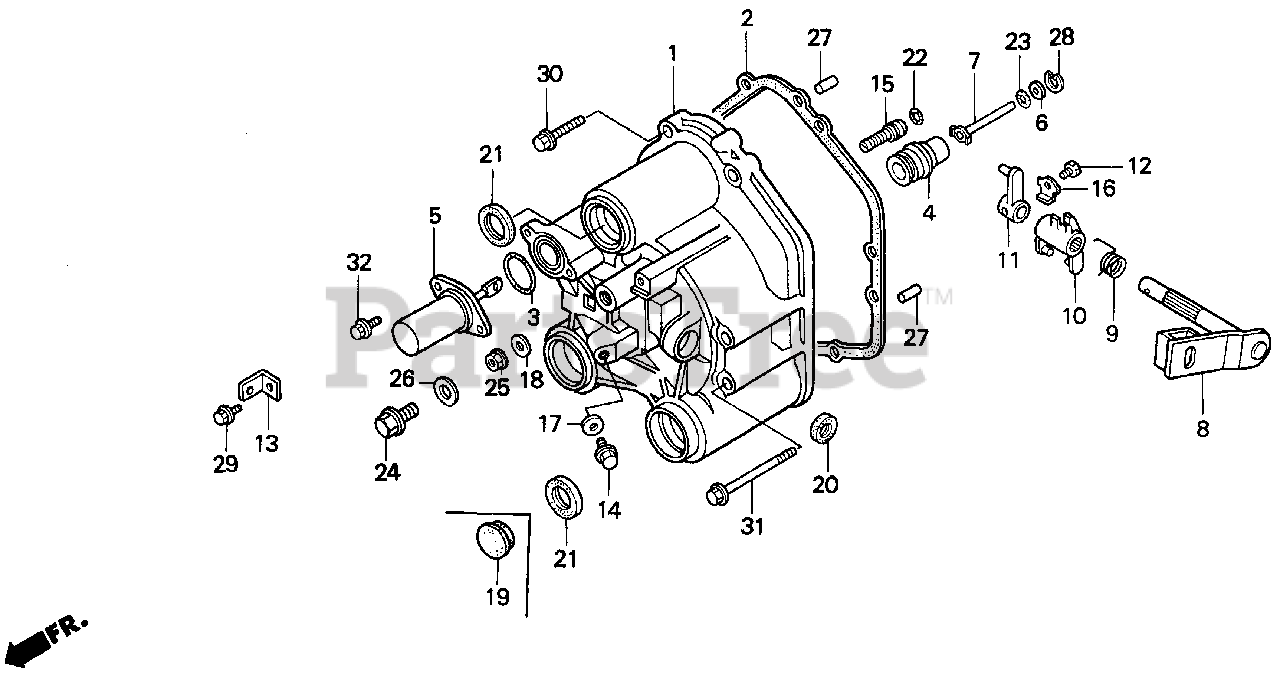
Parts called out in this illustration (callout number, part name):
1	COVER, CLUTCH
2	GASKET, CLUTCH COVER
3	O-RING (37.5X2)
4	ROD, CLUTCH LIFTER
5	DAMPER ASSY., CLUTCH
6	GUIDE B, FEED PIPE
7	FEED PIPE, MAIN CLUTCH
8	LEVER, CLUTCH
9	SPRING, CLUTCH LEVER
10	FORK, CLUTCH LIFTER
11	FORK, CLUTCH DAMPER
12	BOLT, FORK SHAFT SETTING
13	BRACKET, WIRE HARNESS CLIP (H)
14	BOLT, SEALING (8MM)
15	BOLT, ADJUSTING (8MM)
16	WASHER, LOCK (6MM)
17	WASHER (8MM)
18	WASHER (8MM)
19	PLUG, SEAL (36X10)
20	OIL SEAL (14X24X6) (ARAI)
21	OIL SEAL (22X36X6)
22	O-RING (6.8X1.9)
23	O-RING (6X1.5) (NOK)
24	BOLT, DRAIN PLUG (14MM)
25	NUT, FLANGE (8MM)
26	WASHER, DRAIN PLUG (14MM)
27	PIN, DOWEL (8X14)
28	CIRCLIP (INNER) (19MM)
29	BOLT, FLANGE (6X12)
30	BOLT, FLANGE (8X40)
31	BOLT, FLANGE (8X95)
32	BOLT, FLANGE (6X16)
